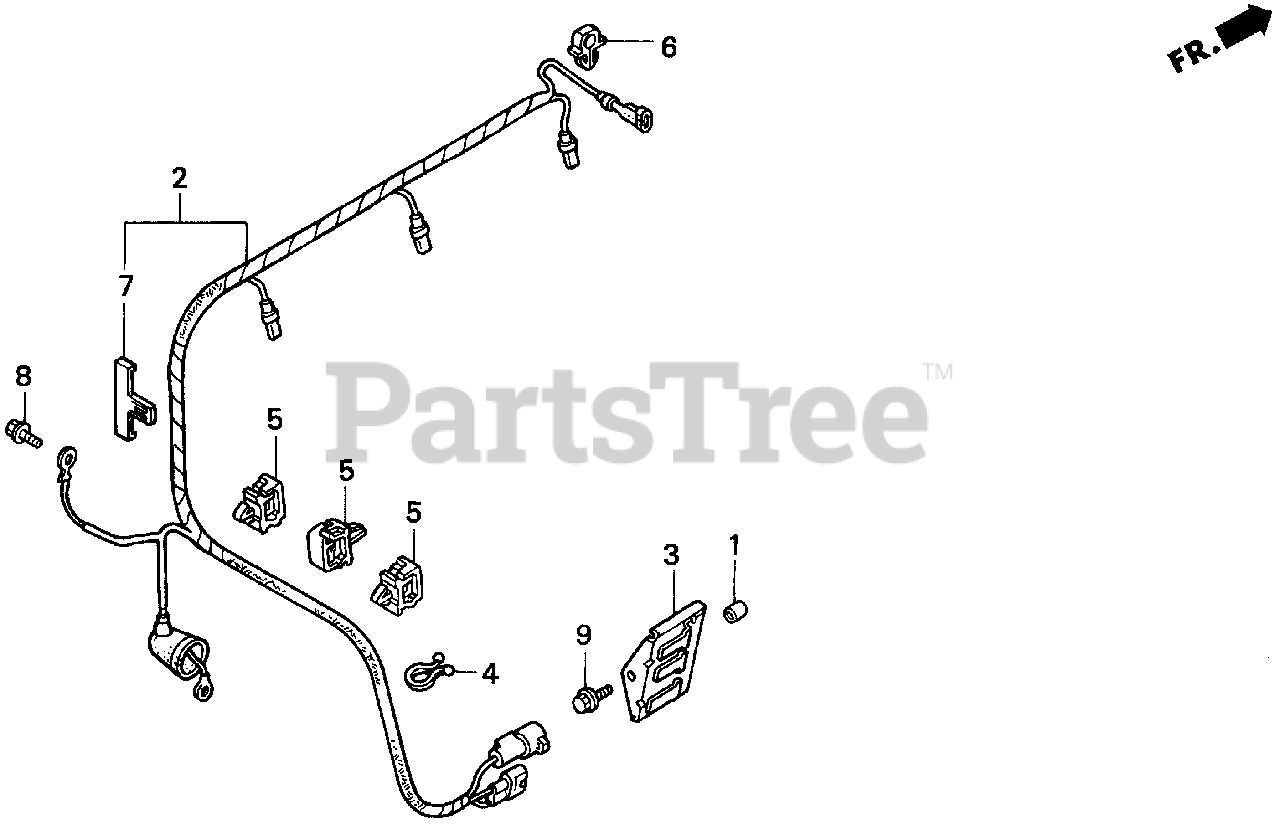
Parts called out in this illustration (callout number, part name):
1	COLLAR, STAY
2	CABLE ASSY., GLOW PLUG
3	BRACKET, CONNECTOR
4	CLIP, PURSE LOCK
5	CLIP, HARNESS (15MM) (BLUE)
6	CLIP, ENGINE STOP SWITCH CORD
7	CLIP, WIRE HARNESS
8	BOLT, FLANGE (6X8)
9	BOLT, FLANGE (6X18)
